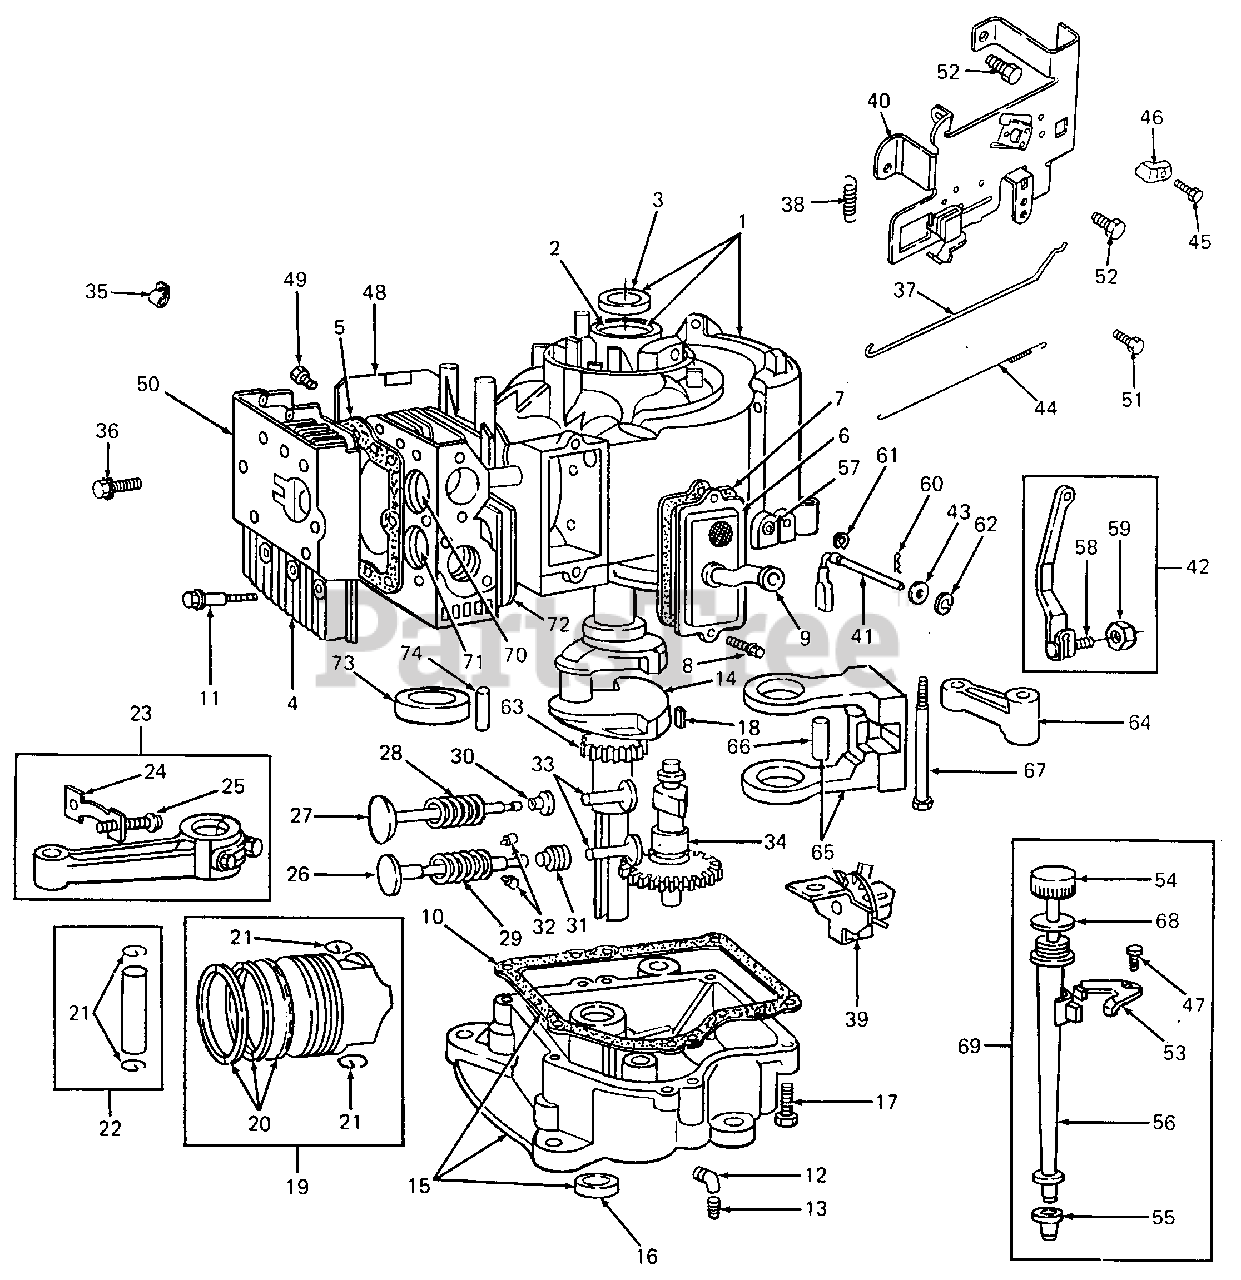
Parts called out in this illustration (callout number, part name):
1	Cylinder Assembly
2	Bearing, Cylinder
3	Seal, Oil
4	Head, Cylinder
5	Gasket, Cylinder Head
6	Breather Assembly
7	Gasket, Valve Cover
8	Screw, Sems
9	Tube, Breather
10	Gasket, Crankcase Cover, 1/64" Thk
11	Screw, Cylinder Head
12	Tube, Oil Drain
13	Plug, Oil Drain
14	Crankshaft
15	Sump, Engine
16	Seal, Oil
17	Screw, Sump Mounting Sems
18	Key, Flywheel
19	Piston Assy, Std
20	Ring Set, Piston, Std
21	Lock, Piston Pin
22	Pin, Assembly, Piston, Std
23	Rod Assembly, Connecting
24	Lock, Connecting Rod Screw
25	Screw, Connecting Rod
26	Valve, Exhaust
27	Valve, Intake
28	Spring, Intake Valve
29	Spring, Exhaust Valve
30	Retainer, Intake Valve
31	Rotocoil, Exhaust Valve
32	Retainer, Exhaust Valve Rotocoil
33	Tappet, Valve
35	Clip, Lead Wire
36	Screw, Hex Hd Washer
37	Link, Governor
38	Spring, Governor
39	Oil Slinger, Governor Gear & Bracket Assembly
40	Plate, Governor Control
41	Crank, Governor
42	Lever Assy, Governor
43	Washer, Governor Crank
44	Spring, Governor Link
45	Screw, Sems
46	Clamp, Casing
47	Screw, Clamp Mounting
48	Shield, Cylinder
49	Screw, Cylinder Shield Mtg Sems
50	Cover, Cylinder Head
51	Screw, Hex Hd
52	Screw, Hex Hd
53	Clamp, Oil Filler Tube
54	Cap & Dipstick, Oil Filler
55	Seal, Filler Tube
56	Tube, Oil Filler
57	Bushing, Governor Crank
58	Bolt, Governor Lever
59	Nut, Hex, #10-24
60	Cotter, Hair Pin
61	Retainer, E-Ring
62	Seal, Oil
63	Gear, Timing
64	Link, Counterweight
65	Counterweight Assembly
66	Pin, Counterweight
67	Screw, Counterweight
68	Seal, Oil Filler Cap
69	Fill Group, Oil
70	Seat, Intake Valve Std
71	Seat, Exhaust Valve Std
72	Guide, Exhaust Valve
74	Pin, Eccentric
